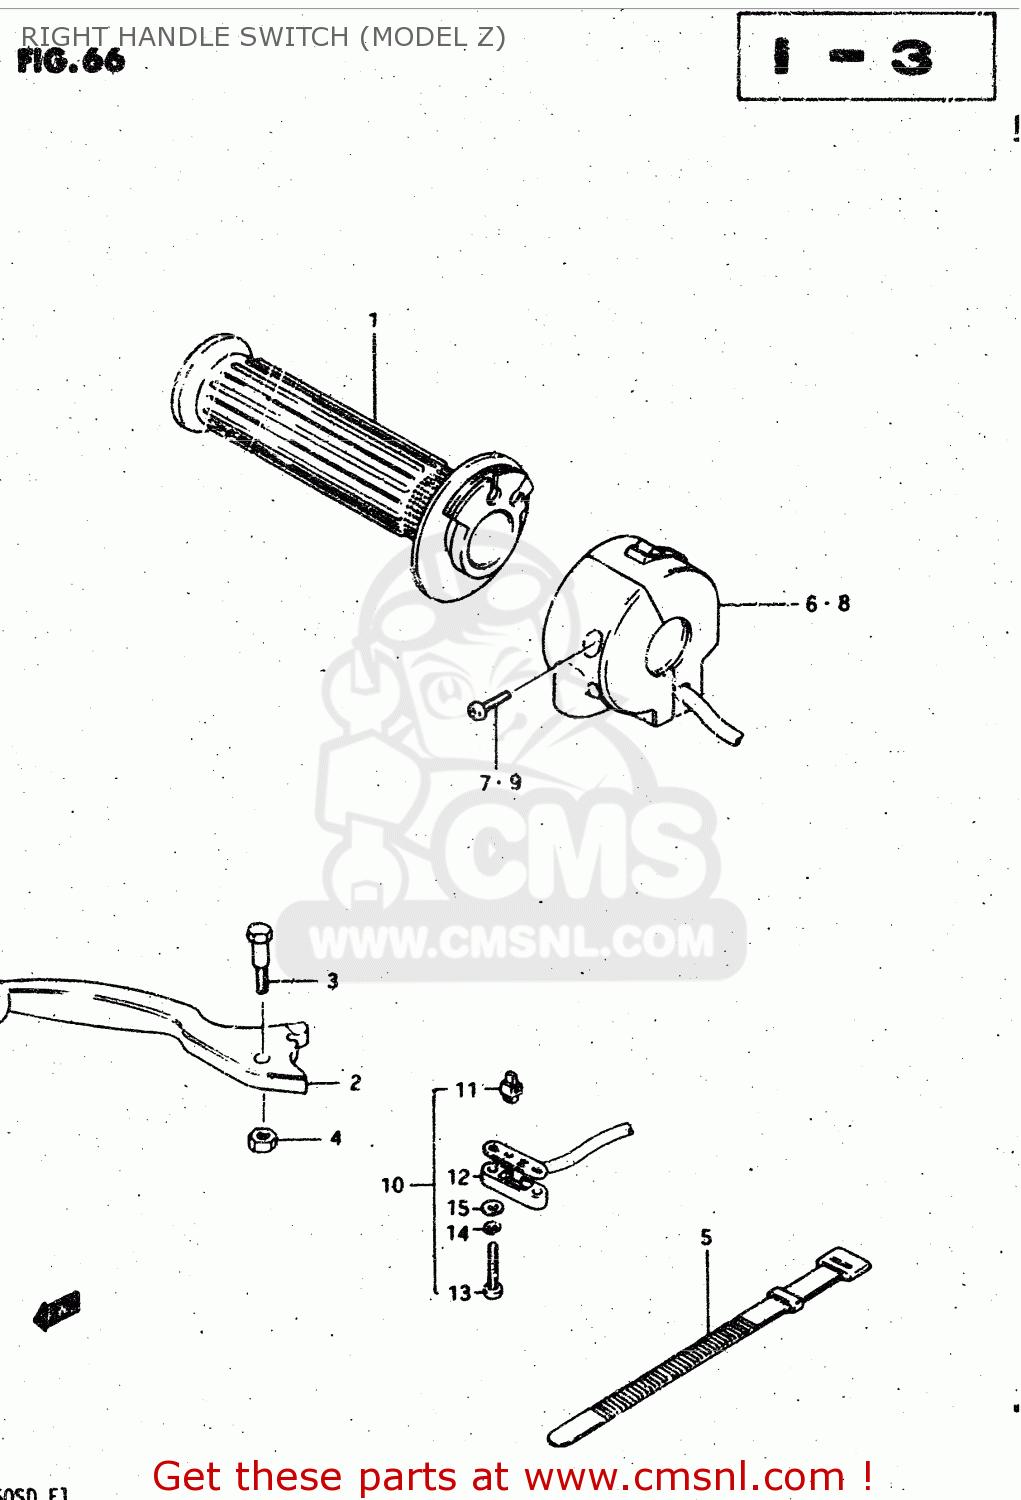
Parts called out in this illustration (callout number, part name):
1	GRIP,THROTTLE
2	LEVER,BRAKE
3	BOLT
4	NUT 6MM
5	CLAMP(L:120)
6	SWITCH ASSY, HANDLE RH
7	SCREW
8	SWITCH ASSY, HARDLE RH
9	SCREW
10	SWITCH ASSEMBLY
11	CONTACT,SWITCH
12	COVER,FR BK TERMINAL BASE
13	SCREW
14	LOCK WASHER
15	WASHER
